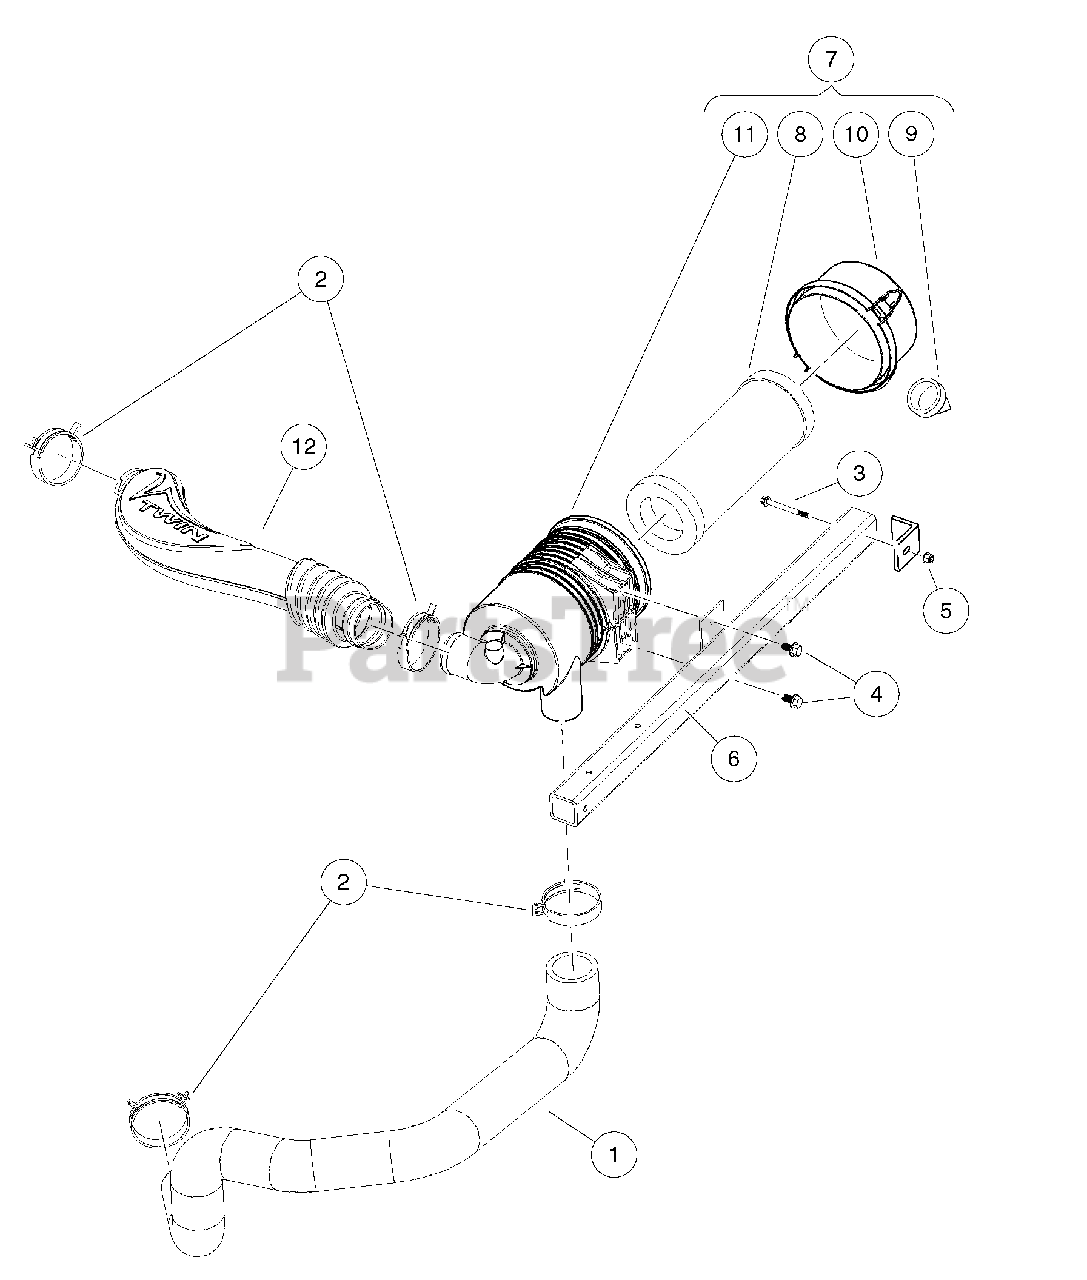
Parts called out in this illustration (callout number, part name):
1	Hose, Intake, Primary
2	Clamp, Hose, Ctb 64mm
3	Bolt, M 6 X 1.0 X 65 Hex, Flange, Head, Black
4	Bolt Flanged Head, M8 X1.25x 16 with Loctite
5	Nut Flg, M6 X 1.0 Nylon
6	Weldment, Support, Air Cleaner
7	Filter, Air, Canister, W/labe
8	Element, Filter, Air, 5 In
9	Valve, Evacuator, Filter Air
10	Cap, Latch Lock, Filter, Air
11	Body, Canister, Filter, Air
12	Hose, Intake, Fh680d
